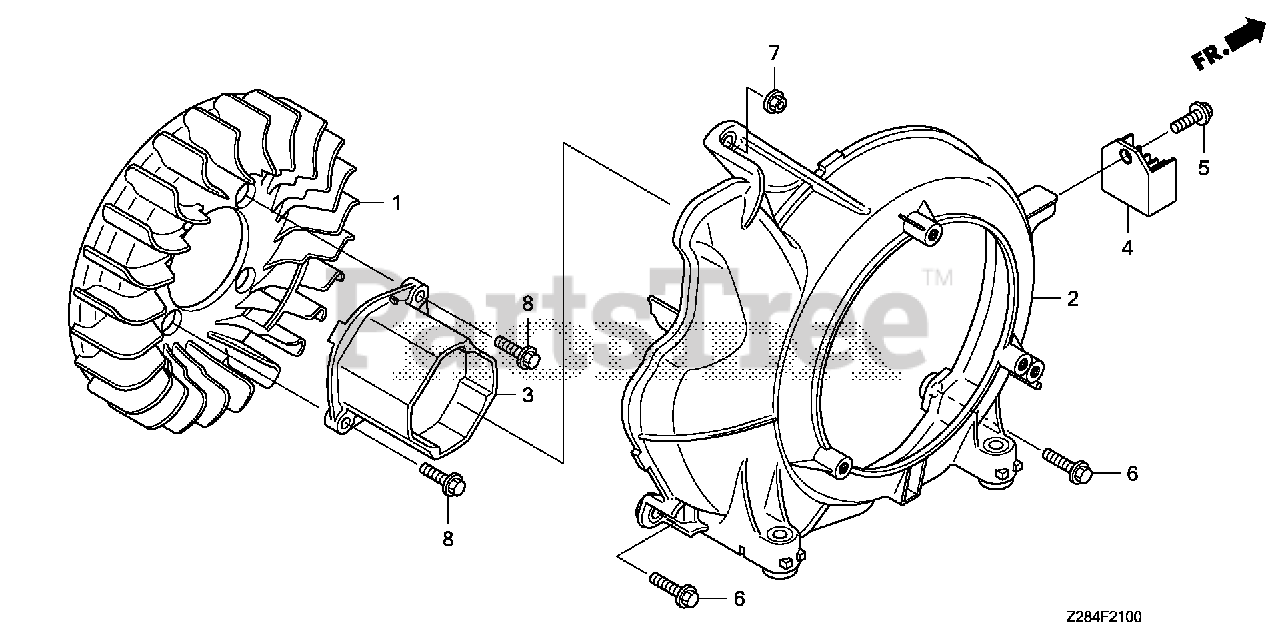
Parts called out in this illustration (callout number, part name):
1	FAN, COOLING
2	COVER, FAN
3	PULLEY, RECOIL STARTER
4	RECTIFIER ASSY.
5	BOLT, FLANGE (6X14) (CT200)
6	BOLT, FLANGE (6X23) (CT200)
7	NUT, FLANGE (6MM)
8	BOLT, FLANGE (6X20)
